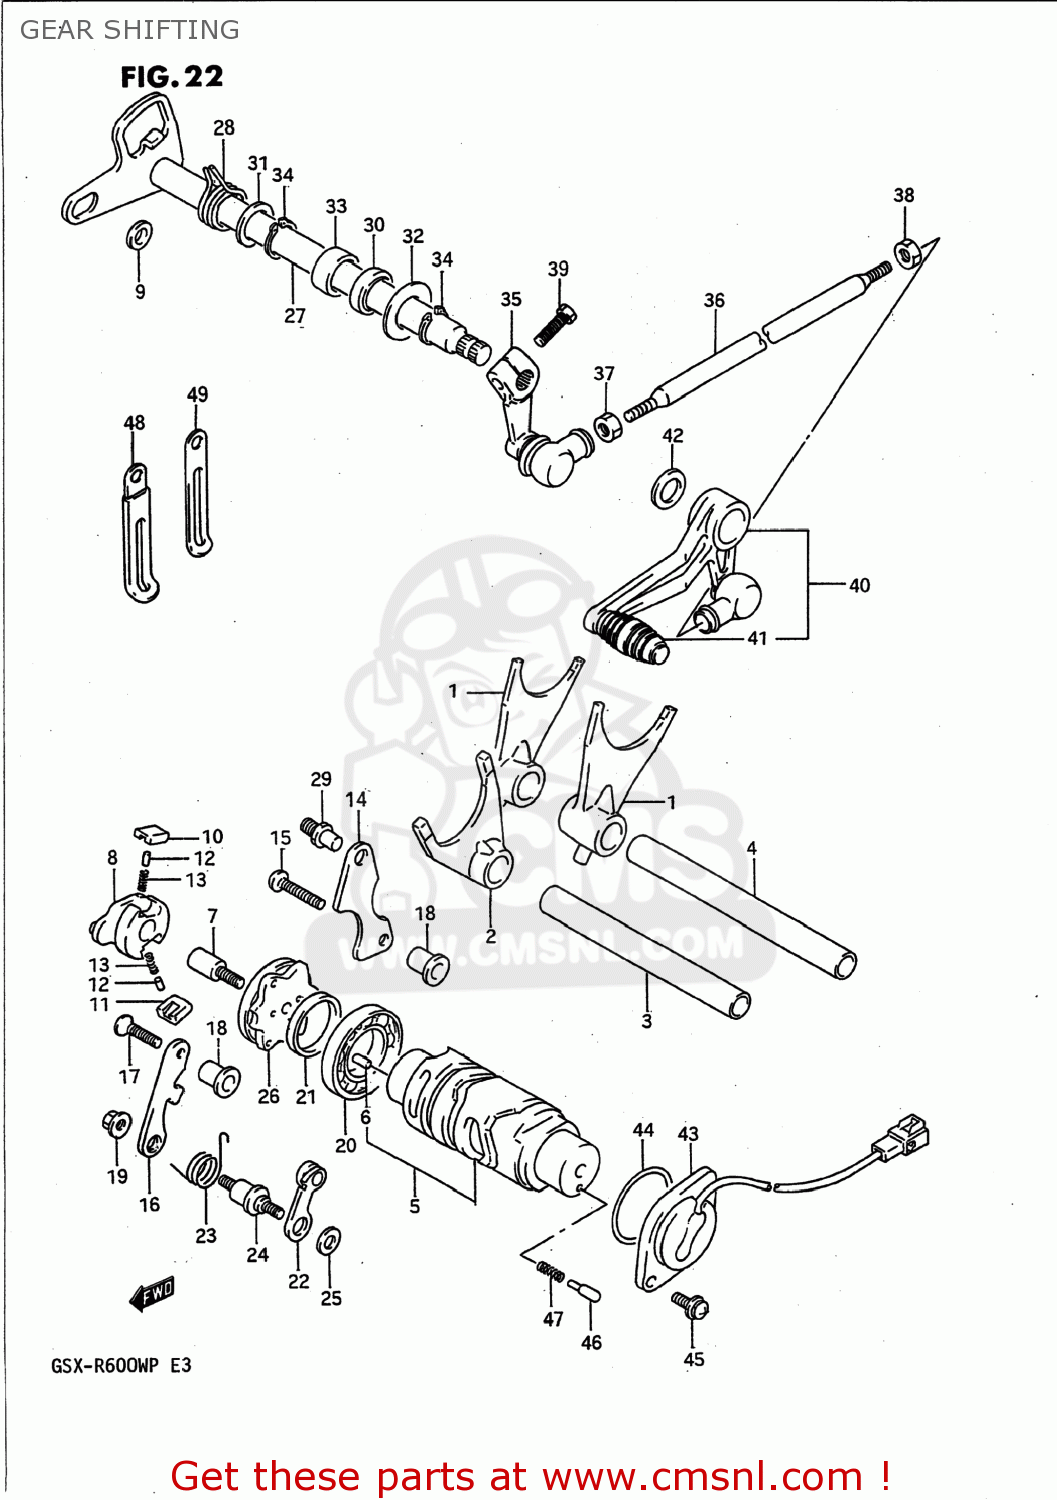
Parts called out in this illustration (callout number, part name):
1	FORK,GEAR SHIFT NO.1
2	FORK,GEAR SHIFT NO.3
3	SHAFT,GEAR SHIFT FORK
4	SHAFT,GEAR SHIFT FORK(L:128)
5	CAM,GEAR SHIFT
6	PIN
7	PIN,SHIFT CAM DRIVEN GEAR
8	SHIFTER,GEAR SHIFT CAM
9	SPACER(7X10X5)
10	PAWL,GEAR SHIFT NO.1
11	PAWL,GEAR SHIFT NO.2
12	PIN(5X8)
13	SPRING
14	LIFTER,GEAR SHIFT PAWL
15	SCREW 6X30
16	GUIDE,GEAR SHIFT CAM
17	SCREW
18	SPACER(6.1X10X16)
19	NUT
20	BEARING
21	WASHER(25X32X3)
22	STOPPER,GEAR SHIFT CAM
23	SPRING,STOPPER ARM
24	SUPPORT,CAM STOPPER ARM
25	WASHER
26	PLATE,GEAR SHIFT CAM
27	SHAFT COMP,GEAR SHIFTING
28	SPRING
29	STOPPER,GEAR SHIFT CAM
30	SEAL,OIL(14X22X7.3)
31	WASHER,THRUST
32	WASHER
33	BEARING(14X20X12)
34	CIRCLIP
35	ARM,GEAR SHIFT LINK
36	ROD,GEAR SHIFT LINK
37	NUT
38	NUT 6MM
39	BOLT
40	LEVER ASSEMBLY,GEAR SHIFTING
41	RUBBER,GEAR SHIFT PEDAL
42	WASHER(18X24X1)
43	TERMINAL BASE ASSY,NEUTRAL
44	O RING(D:2.4,ID:36.5)
45	SCREW
46	PIN(5X15.5)
47	SPRING
48	CLAMP L:35
49	CLAMP
